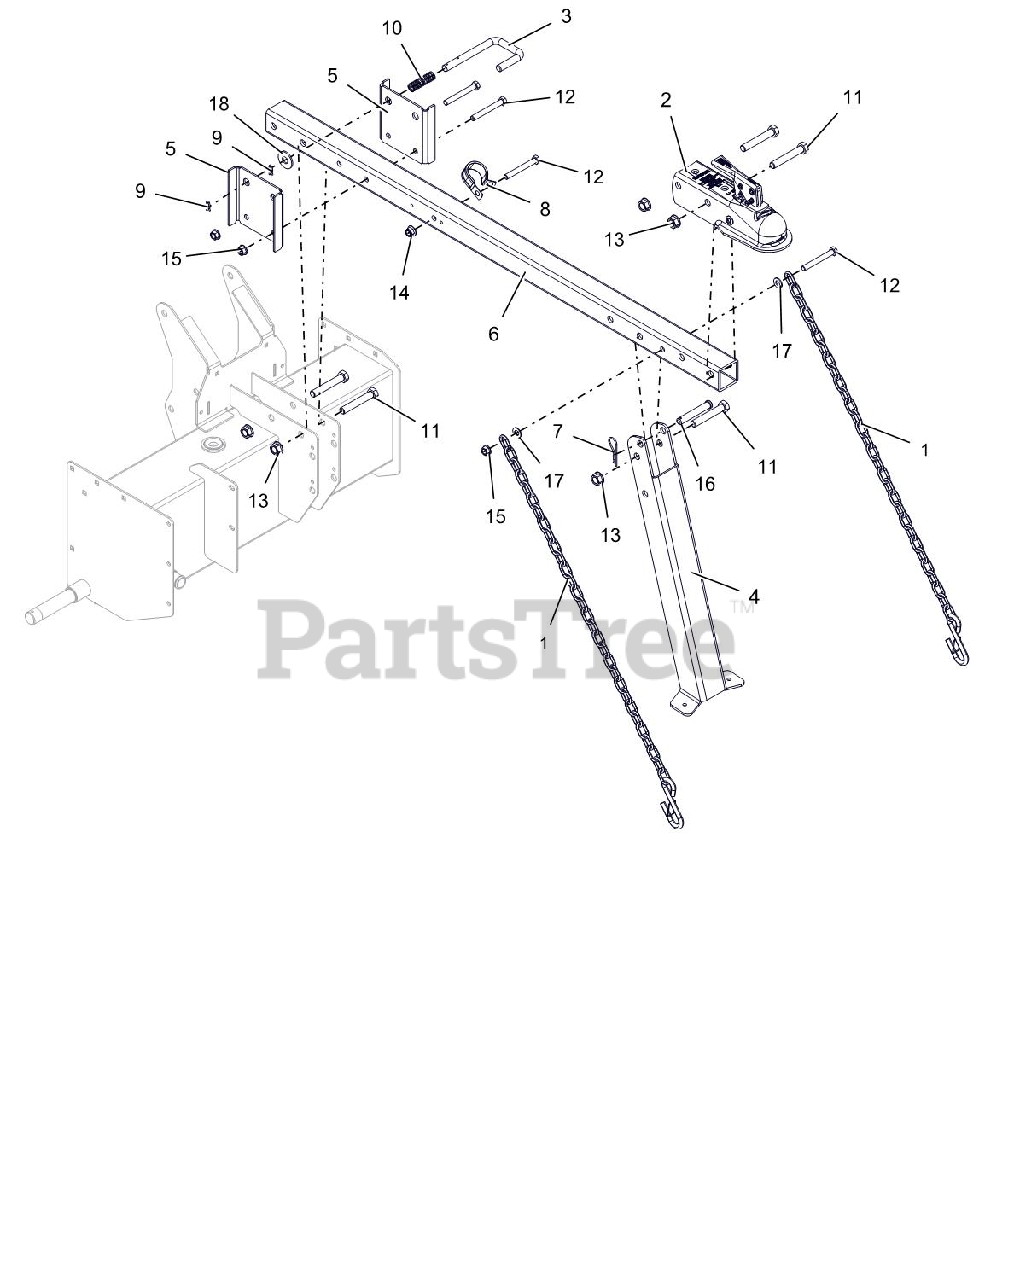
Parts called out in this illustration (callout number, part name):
1	CHAIN, SAFETY 3/16"-30LINK
2	COUPLER-BALL 2.000"
3	LOCK, BEAM
4	LEG SUPPORT-FRONT
5	GUIDE, LOCK DOWN
6	DRAWBAR TUBE W/SAFETY DECAL-22
7	HAIRPIN, #7 CLIP .094X2.31 YWZ
8	CLAMP, CUSHIONED STEEL 1.25
9	CLIP, SPRING
10	SPRG, COMP .058X.65X2.13 WLD15
11	@BLT-HEX .50-13X3.00 GR5 YWZC
12	@BLT-HEX .38-16X3.00 GR5 YWZC
13	NUT-LK-CTR-FLG .50-13 YWZC
14	@NUT-LK-NYL-FLG .38-16 YWZC
15	@NUT-LK-TOP-FLG .38-16 YWZC
16	PIN, CLEVIS .50 X 3.00 YWZC
17	@WSHR-FL-STL.406X.812X.065 YWZ
18	@WSHR-FL-STL.563X1.38X.109YWZC
